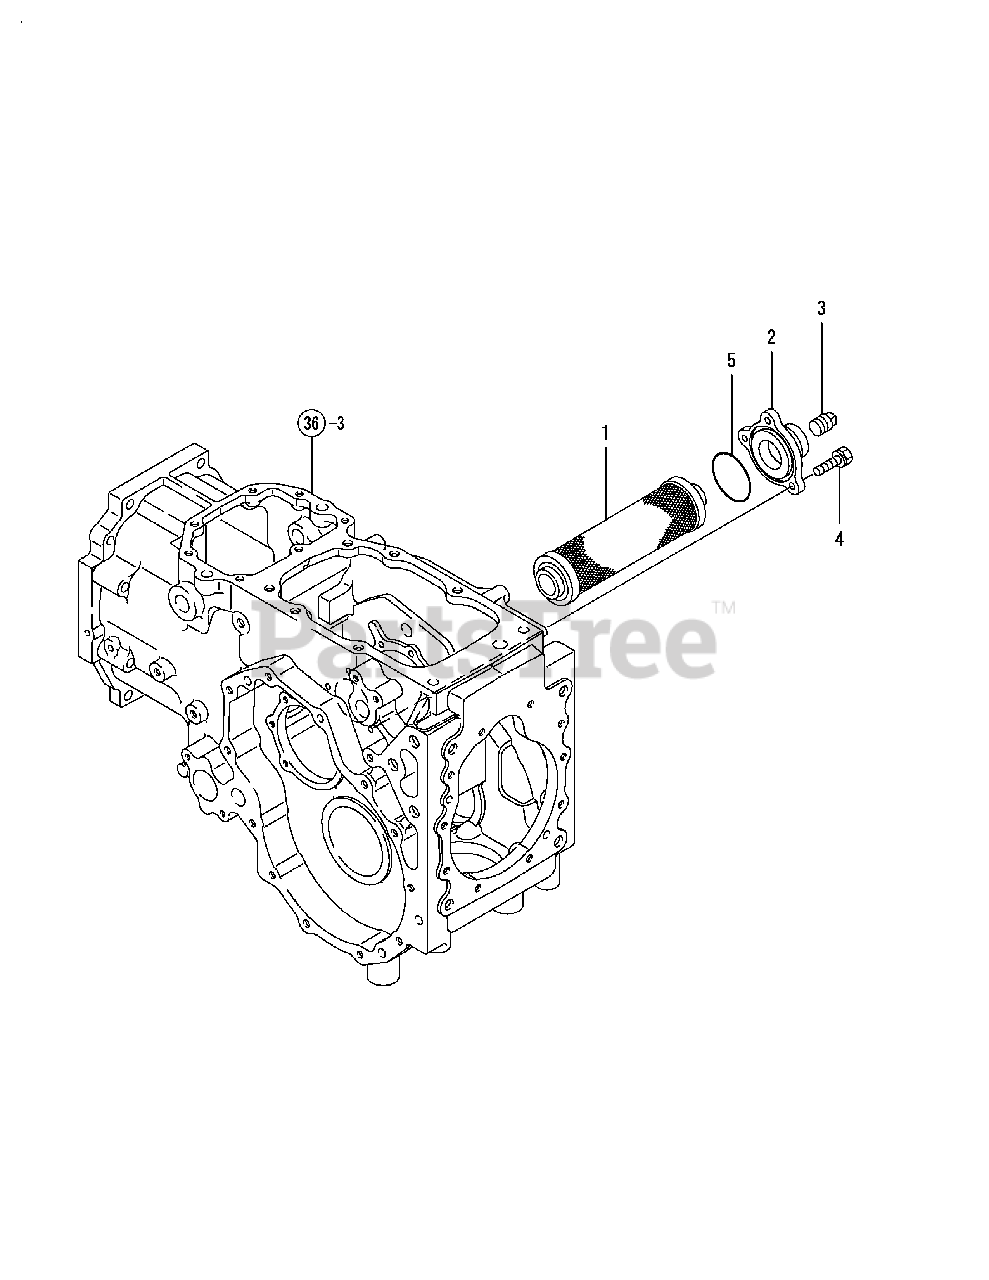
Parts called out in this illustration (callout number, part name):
1	FILTER, SUCTION
2	COVER, OIL STRAINER
4	BOLT M 8X 20 PLATED
5	O-RING 1A G-50.0
